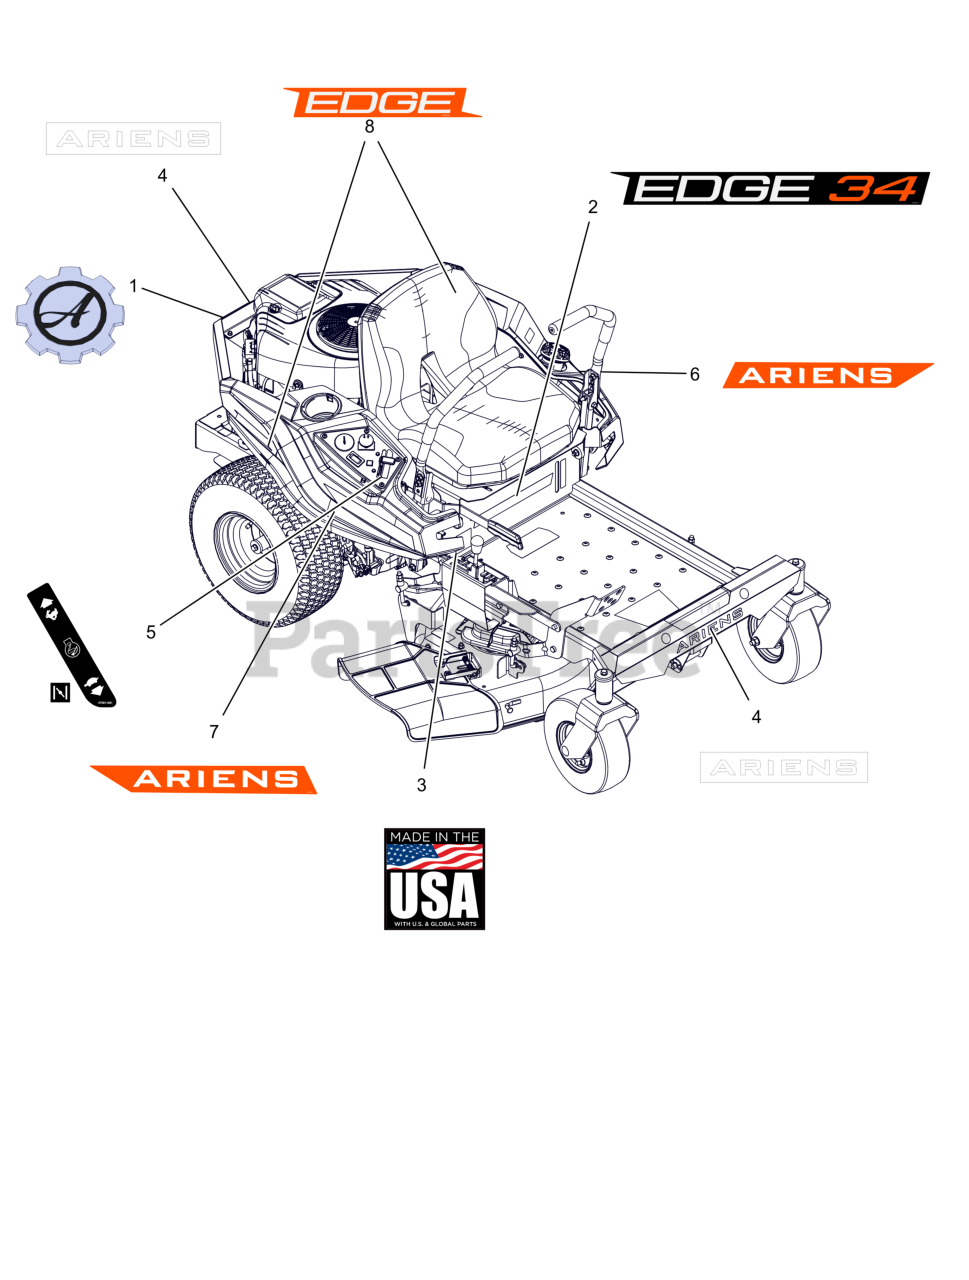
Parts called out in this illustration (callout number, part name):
1	DECAL, ARIENS-GEAR BADGE -THK
2	DECAL, EDGE 34 - KICKPLATE
3	DECAL, MADE IN USA
4	DECAL - ARIENS 9.625"
5	DECAL, SPEED CONTROL
6	DECAL, ARIENS FENDER LH
7	DECAL, ARIENS FENDER RH
8	DECAL, EDGE FENDER
